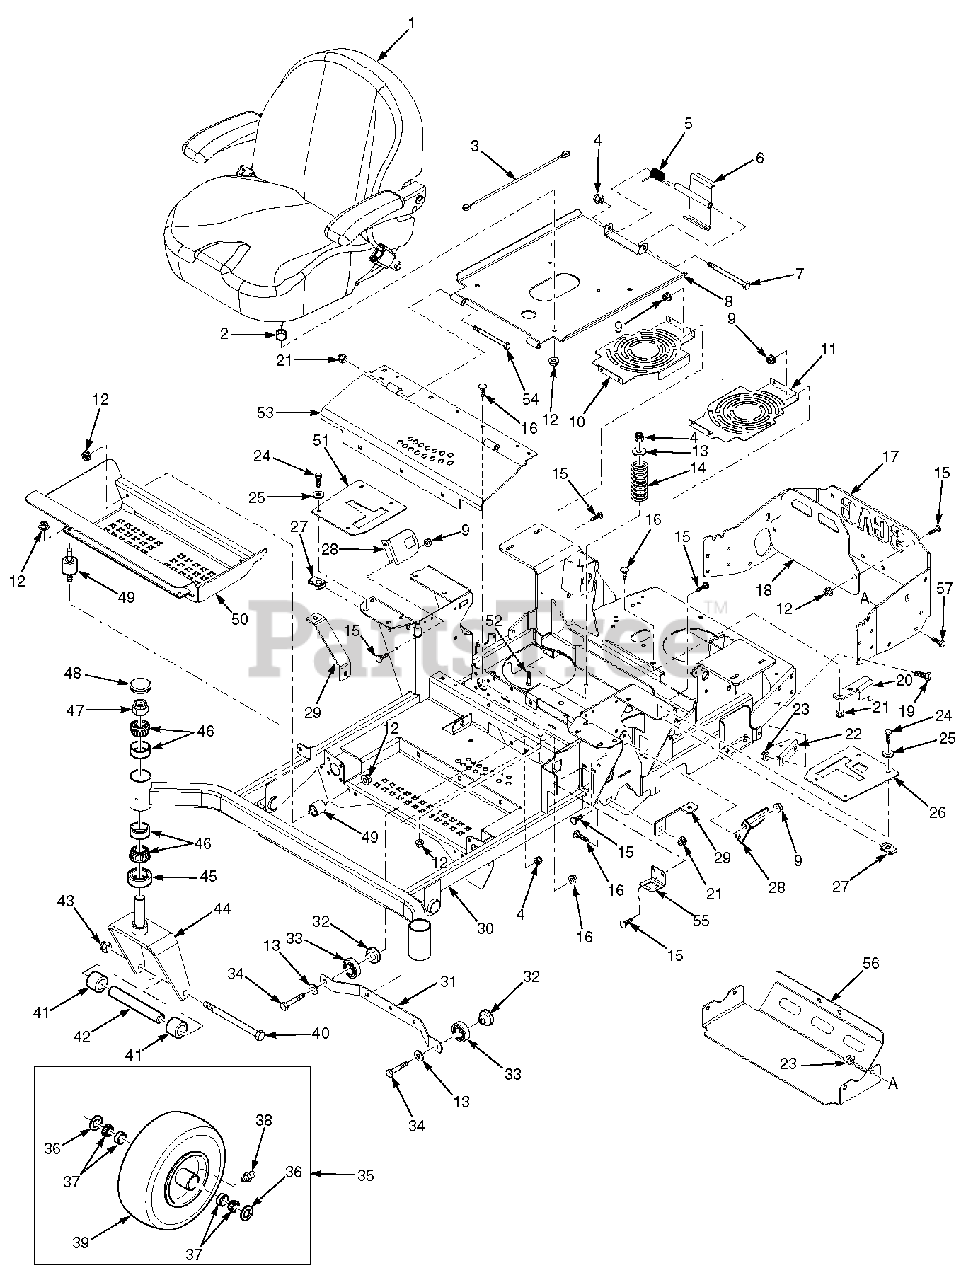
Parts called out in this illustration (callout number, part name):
1	Seat Assembly
2	Spacer
3	Cable, Seat Stop
4	Nut, Elastic Stop 3/8-16
5	Spring, Seat Latch
6	Weldment, Seat Latch
7	Bolt, Hex Head 3/8-16 x 6"
8	Seat Plate Weldment
9	Nut, Serrated Flange 1/4-20
10	Fan Cover, RH
11	Fan Cover, LH
12	Nut, Serrated Flange 5/16-18
13	Flatwasher, 3/8-.391 x .938 x .105
14	Spring, Seat
15	Bolt, Carriage 1/4-20 x 1"
16	Bolt, Carriage 5/16-18 x 3/4"
17	Bumper - SPZ
18	Guard, Engine
19	Bolt, Hex Head 3/8-16 x 1"
20	Anti-Rotation Bracket
21	Nut, Elastic Stop 5/16-18
22	Bracket, Dump Valve
23	Nut, Serrated Flange 3/8-16
24	Bolt, Hex Head 1/4-20 x 1"
25	Flatwasher, 1/4-.312 x .750 x .065
26	Control Plate w/Decal, LH
27	U-Nut, 1/4-20
28	Bracket, Switch Mount
29	Bracket, Tank Mount, SPZ52
29	Bracket, Tank Mount, SPZ61
30	Mainframe Assy., w/Decals - SPZ52
30	Mainframe Assy., w/Decals - SPZ61
31	Support, Deck Guide
32	Spacer, Bearing
33	Bearing
34	Bolt, Hex Head 3/8-16 x 2-1/2"
35	Wheel Assembly - SPZ52
35	Wheel Assembly - SPZ61
37	Bearing
38	Fitting, Grease
39	Tire, 13 x 5-6 - SPZ52
39	Rim - SPZ52
39	Tire, 13 x 6.5-6 - SPZ61
39	Rim - SPZ61
40	Bolt, Hex Head 1/2-13 x 7-1/2"
40	Bolt, Hex Head 1/2-13 x 9-1/2"
41	Spacer, Caster Wheel
42	Sleeve, Caster Wheel - SPZ52
42	Sleeve, Caster Wheel - SPZ61
43	Nut, Elastic Stop 1/2-13
44	Yoke Weldment - SPZ52
44	Yoke Weldment - SPZ61
45	Seal, 2" OD x 1.625 ID
46	Bearing Set
47	Nut, Elastic Stop 1"-14
48	Grease Cap
49	Rubber Isolator
50	Footplate Weldment, SPZ52
50	Footplate Weldment, SPZ61
51	Control PLate w/Decal, RH
52	Bolt, Carriage 3/8-16 x 1-1/4"
53	Deck Lift Cover w/Decal, SPZ52
53	Deck Lift Cover w/Decal, SPZ61
54	Bolt, Hex Head 5/16-18 x 3-3/4"
55	Switch Bracket
56	Heat Shield
57	Bolt, Hex Head 3/8-16 x 3/4"
